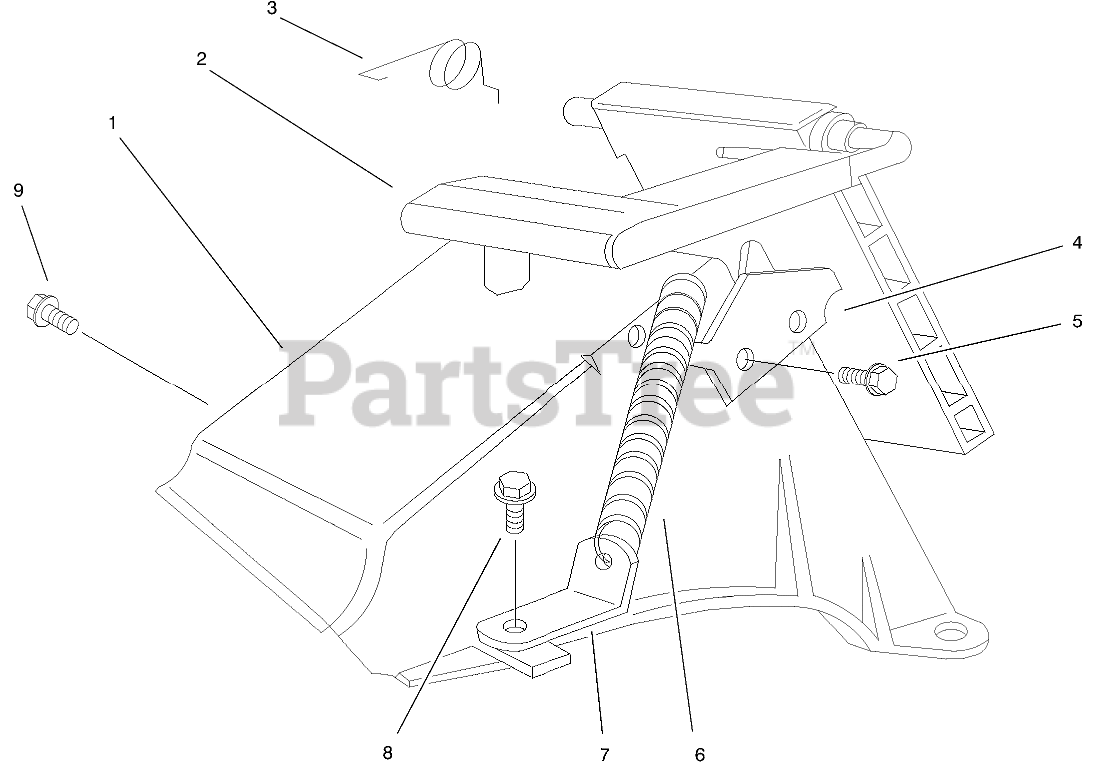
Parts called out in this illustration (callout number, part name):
1	Discharge Tunnel (only on: 20043)
2	Discharge Door ASM (only on: 20043)
3	Spring-Door (only on: 20043)
4	Latch-Plate (only on: 20043)
5	Screw-Plastite (only on: 20043)
6	Retainer-Door (only on: 20043)
7	Bracket-Spring (only on: 20043)
8	Screw-HWH (only on: 20043)
9	Screw & Washer ASM (only on: 20043)
